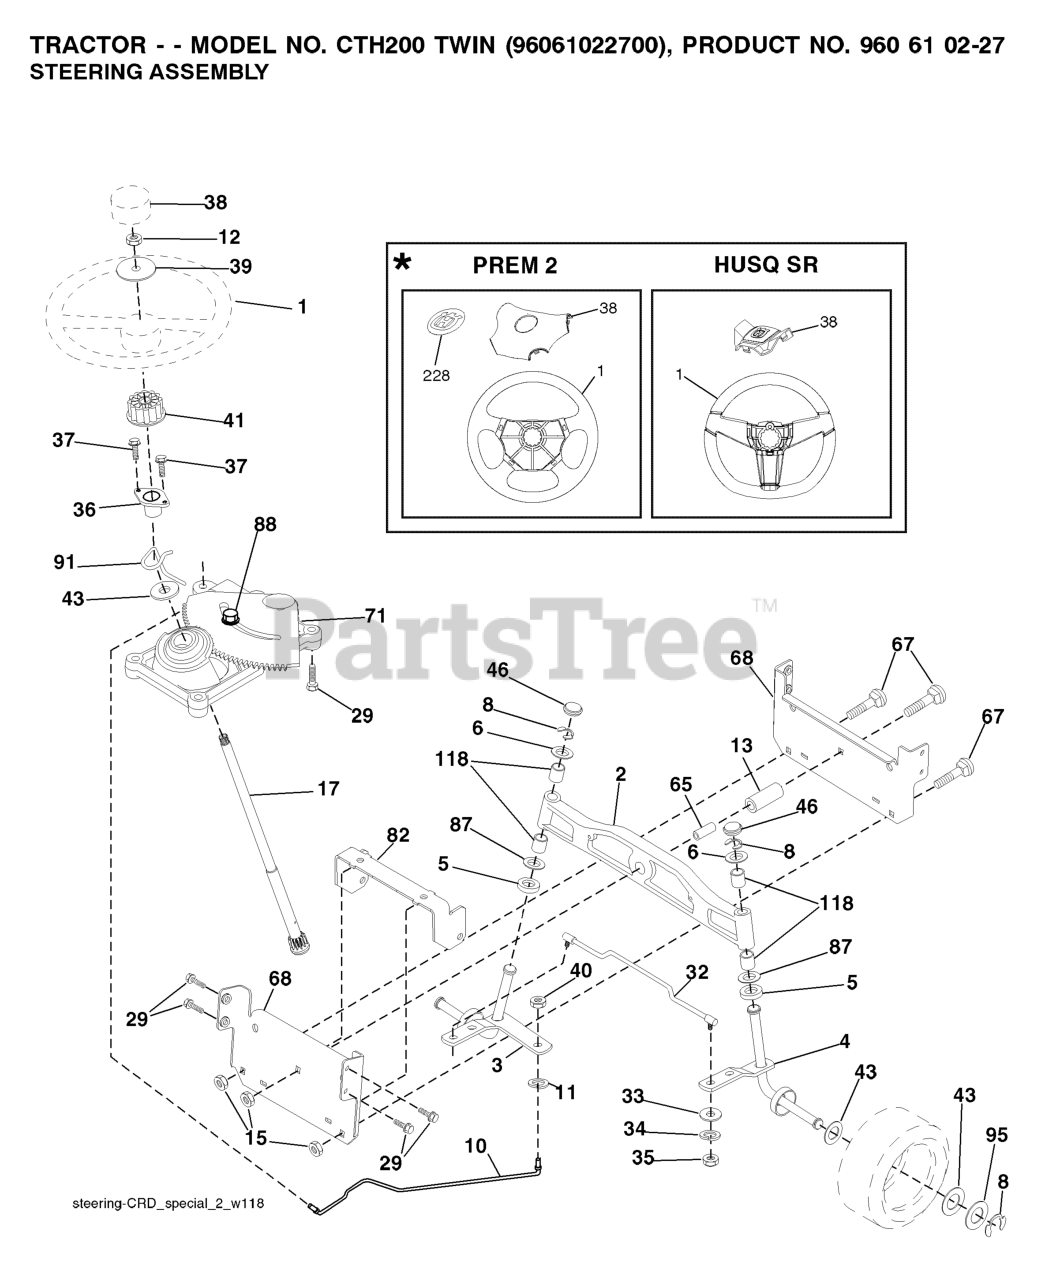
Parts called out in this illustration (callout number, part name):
5	DASH.ASM.HUSQ.GT.E.RECT.W/CK
14	HOOD
15	LENS.LH.TEX.GT.HUSQ.CL
18	GRILL.ASM.HUSQ.TG/CRD.W/TRIM
25	LENS.RH.TEX.GT.HUSQ.CL
34	PLATE.ENGINE.WELDED.CHASSIS
36	SCREW 5/16"
37	FENDER.PNT.TX.GT.CH/FW.ORANGE
52	LOCKNUT
58	BRKT.SUPPORT.FNDR/TANK
68	Screw 5/16-18 x 1/2 Hex, Self Tapping 5/16-18 x 1/2
130	SCREW.#10 X 0.750.BOS
137	BUMPER DASH
150	AIR.DUCT.HOOD.TEX.GT.HUSQ
152	SHIELD.BROWNING.W/TEX
162	SCREW.HI-LO.CONSOLE
165	SUPPORT.TANK.REAR.W/TEX
175	PLATE.CROSSMEMBER.HUSQ
176	SCREW.#10-24X5/8.RN.QU
177	BUSHING, STEERING
178	CARGO.ASM.NET.TXGT.W/C
180	CHASSIS.GT.SLOPED.DRAWBAR.
181	BUSHING.MNT.FEND.CRGO.
182	DASH.LOWER.COMMON.12V.ADAPTOR
183	BOLT.5/16-18X1-1/4 FULL.THREAD
189	SCREW
194	NUT.71038.31-18.HEX.NYLOCK
196	RP CONSOLE.ASM.DECKLFT.W/
199	PLATE.DECK.LIFT.HUSQVARNA.GT
202	VENT.SIDE.HOOD.HUSQ.RH.GREY
203	VENT.SIDE.HOOD.HUSQ.LH.GRAY
204	HOOD VENT
205	SKIRT.HOOD.SIDE.HUSQ.RH.GREY
206	SKIRT.HOOD.SIDE.HUSQ.LH.GREY
207	BEZEL.RH.TEX.GT.HUSQ
208	BEZEL.LH.TEX.GT.HUSQ
209	INSERT.HEX.GRILL.HUSQ.GREY
210	INSERT.HEX.GRILL.HUSQ.
211	INSERT.HEX.GRILL.HUSQ.
212	INSERT.HEX.GRILL.HUSQ.
213	BOLT
214	CLIP.RETAINER.TINNER.
217	ROD.PIVOT.HOOD
218	X-PIECE.HOOD.STOP.NON/
221	REFLECTOR.LH.TEX GT HU
228	STUD.FASTNER.W/ANTI-ROTATE
233	BOLT.SHOULDER
234	BUMPER.HOOD.TEX.HUSQVARNA
235	SPACER FENDER
236	NUT.CENTERLOCK.5/16-
289	PLUG.N/CRUISE.COMMON.YT/GT.BLK
296	TRIM.HUSQ.TG/CRD.SERVICE
298	NUT PUSH M
299	RP LOGO
